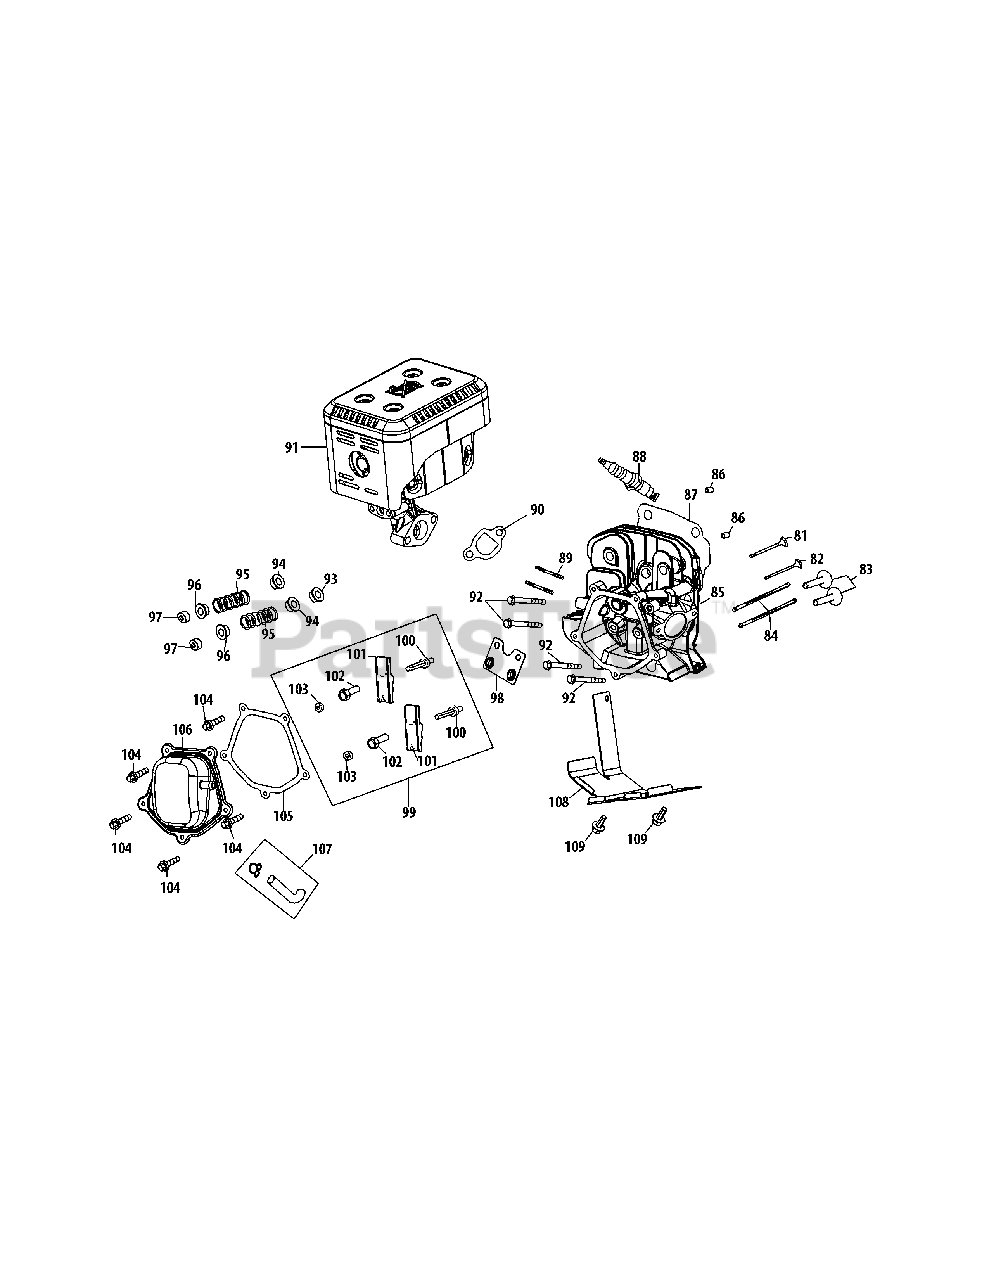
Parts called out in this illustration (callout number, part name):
81	Exhaust Valve
82	Intake Valve
83	Tappet
84	Push Rod Kit
85	Cylinder Head Assembly
86	Dowel Pin 12×20
87	Gasket,Cylinder Head
88	Spark Plug/F6Rtc
89	Muffler Stud M8×48.5
89	Muffler Stud Assembly
90	Muffler Gasket
91	Muffler Assembly
92	Bolt M10×1.25×80
93	Intake Valve Seal
94	Valve Spring Retainer
95	Valve Spring
96	Retainer,Ex.Valve Spring
97	Adjuster,Exh Valve
98	Push Rod Guide
99	Rocker Arm Assembly
100	Bolt,Pivot
101	Rocker Arm
102	Adjusting Nut ,Valve
103	Nut,Pivot Locking
104	Valve Cover Bolt
105	Valve Cover Gasket
106	Valve Cover
107	Breather Hose Assembly
108	Air Shield
109	Bolt M6×12
